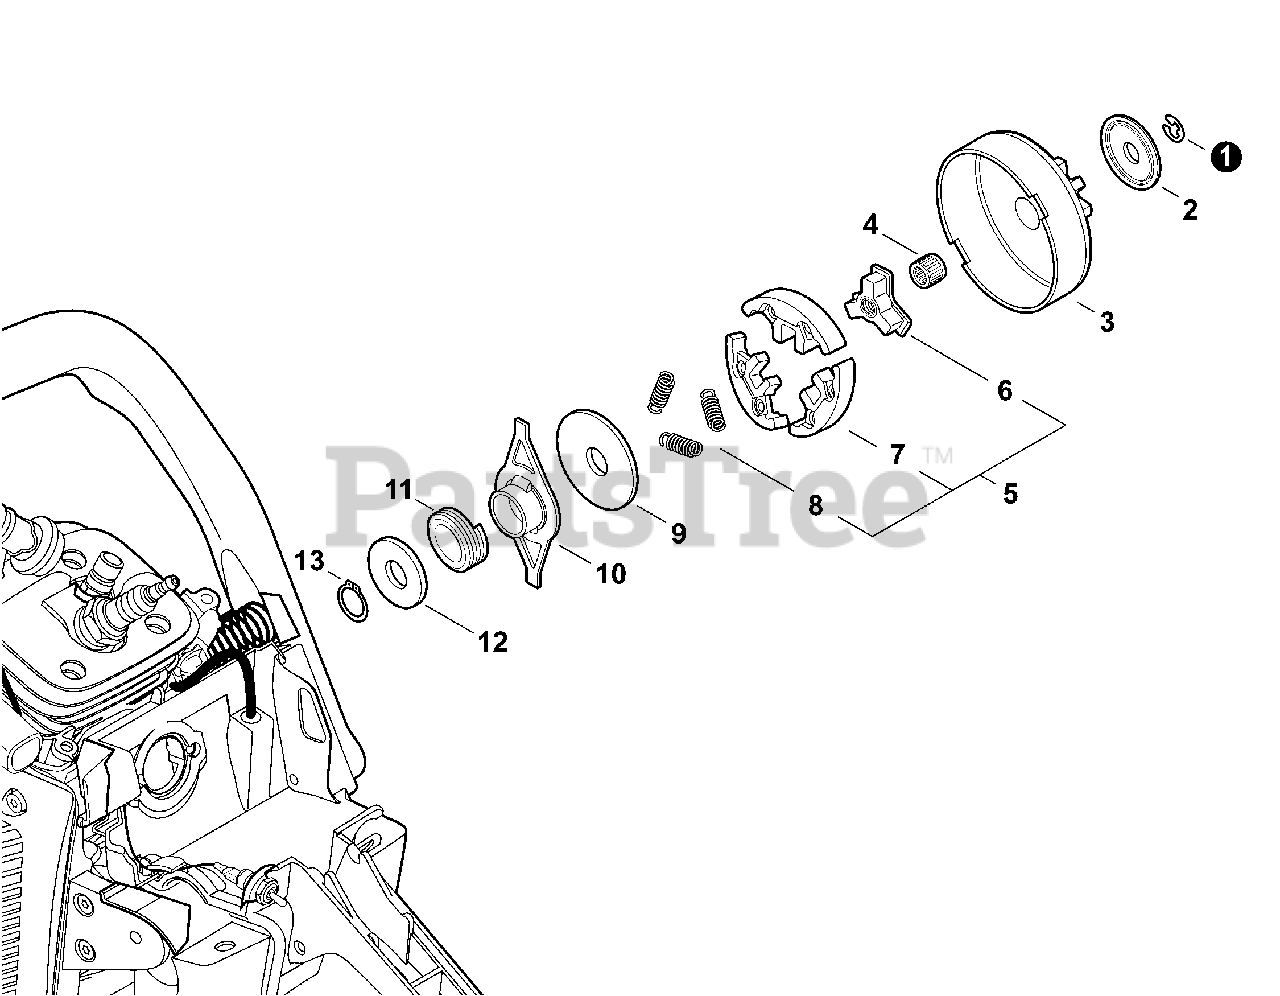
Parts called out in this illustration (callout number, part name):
1	RING, RETAINING - 8
2	WASHER - 10
3	DRUM, CLUTCH
4	BEARING, NEEDLE - 10
5	CLUTCH ASY
6	HUB, CLUTCH
7	CLUTCH SHOE SET
8	SPRING, CLUTCH
9	PLATE, CLUTCH
10	COLLAR - 14
11	GEAR, WORM
12	WASHER - 15
13	RING, RETAINING - 15
